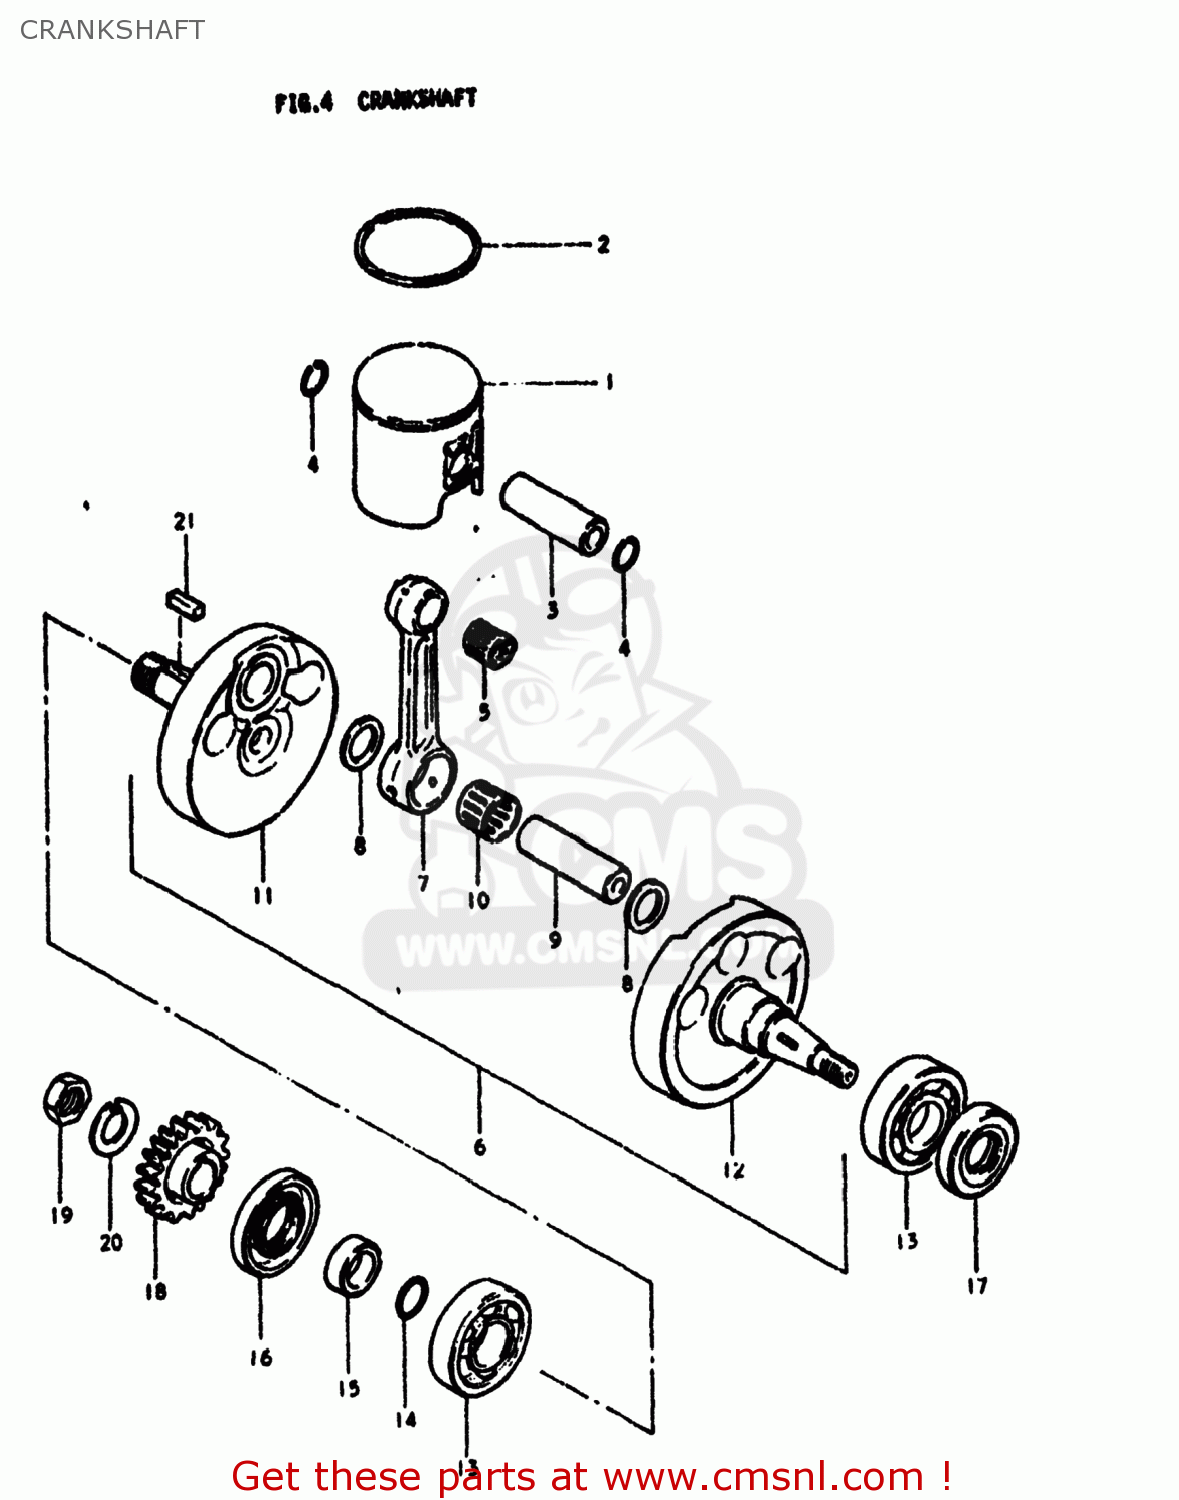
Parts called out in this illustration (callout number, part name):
1	PISTON
2	RING,PISTON
3	PIN,PISTON (18MM)
4	CIRCLIP
5	BEARING(18X22X22)
6	CRANKSHAFT ASSEMBLY
7	ROD,CONNECTING
8	WASHER(24X29X2)
9	PIN,CRANK
10	BEARING
11	CRANKSHAFT
12	CRANKSHAFT,LEFT
13	BEARING
14	O RING(D:2.4,ID:21.8)
15	SPACER (22X37X12.5)
16	SEAL,OIL(37X62X9)
17	SEAL,OIL(24X50X9)
18	GEAR,PRIMARY DRIVE
19	NUT
20	WASHER
21	KEY
